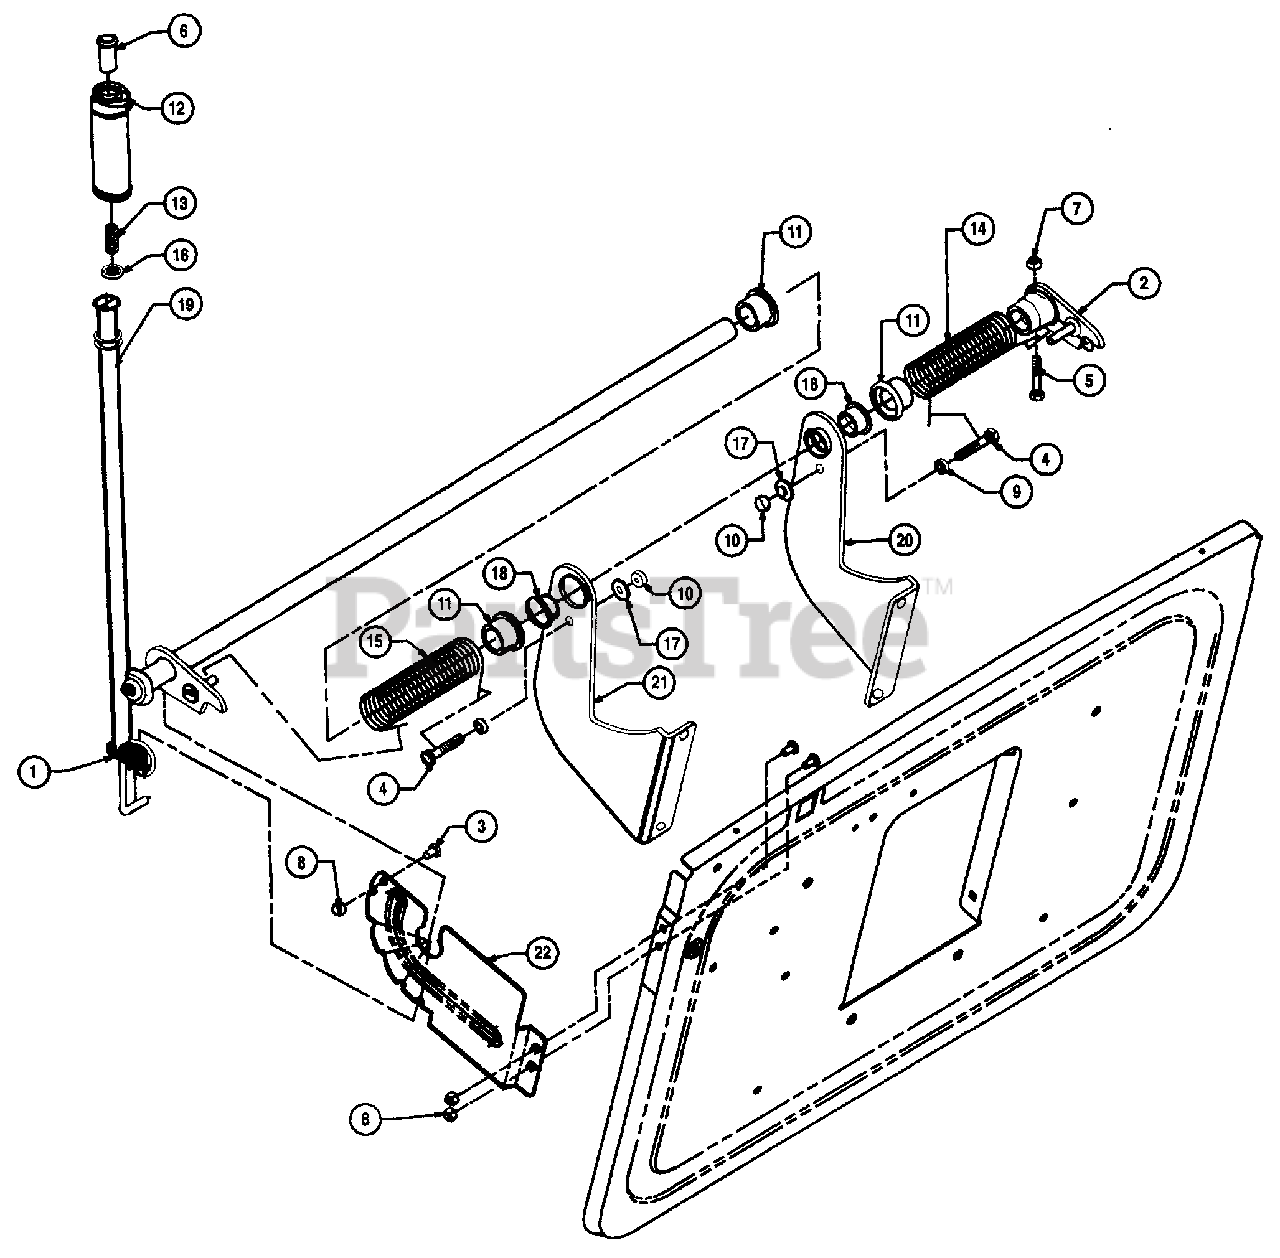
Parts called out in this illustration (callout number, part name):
3	Pan Hd. Mach. Scr. 1/4-20 x .5" Lg.
4	Hex Bolt 5/16-24 x 1.75" Lg. (Gr. 5)
5	Hex Bolt 1/4-28 x 1.75" Lg. (Gr. 5)
6	Handle Button
7	Hex L-Nut 1/4-28 Thd.
8	Hex Ins. L-Nut 1/4-20 Thd.
9	Hex Jam Nut 5/16-24 Thd.
10	Hex Nut 5/16-24 Thd. (Gr. 5)
11	Spring Retainer
13	Comp. Spring
14	Torsion Spring-L.H.
15	Torsion Spring-R.H.
16	FL-Wash. .312" I.D. x .75" O.D.
17	Bell-Wash. .34" I.D. x .87" O.D.
18	Flange Bearing .88" I.D.
